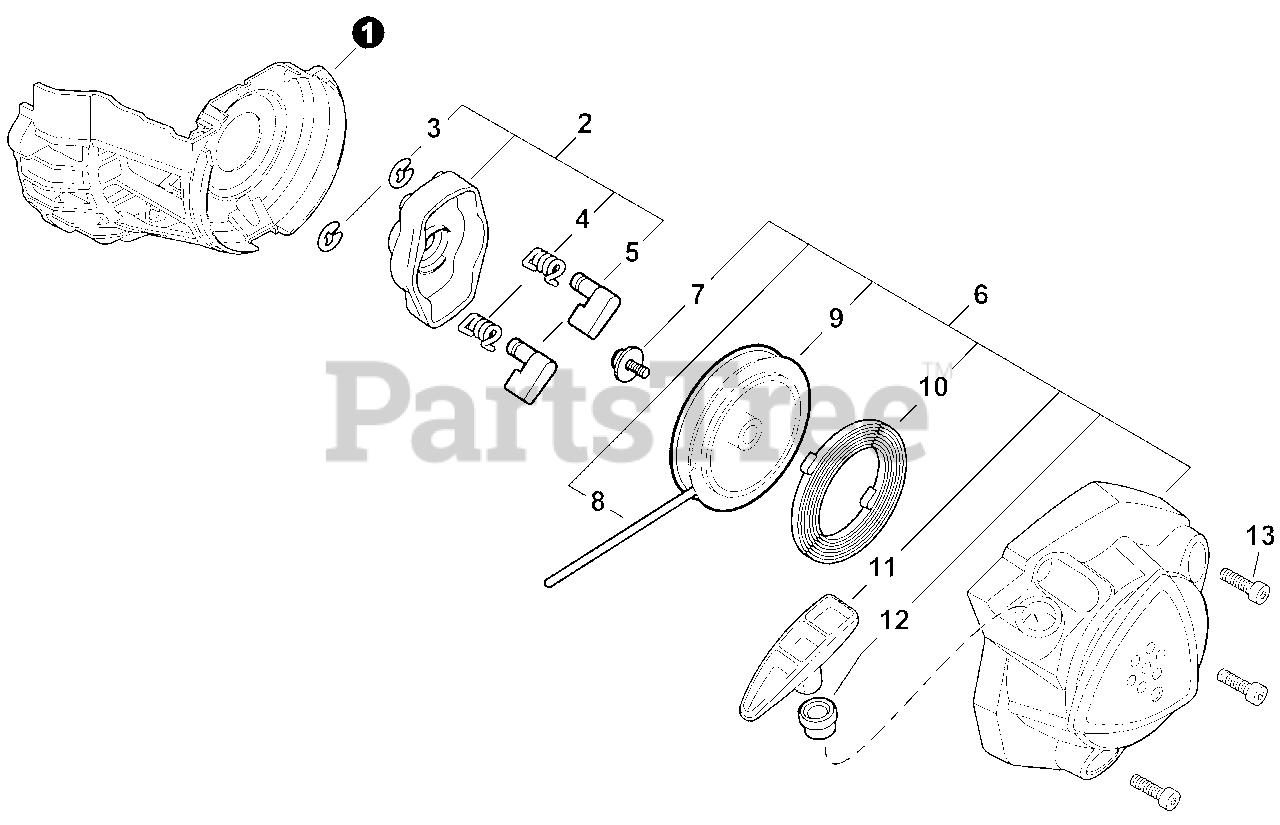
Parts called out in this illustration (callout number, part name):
1	SHIELD, DEBRIS
2	PAWL ASSY, STARTER
3	E-RING 4
4	SPRING, RETURN
5	PAWL, STARTER
6	STARTER ASSY
7	SCREW
8	ROPE, STARTER
9	REEL, ROPE
10	SPRING, RECOIL
11	GRIP, STARTER
12	GUIDE, ROPE
13	BOLT, TORX 5×16
